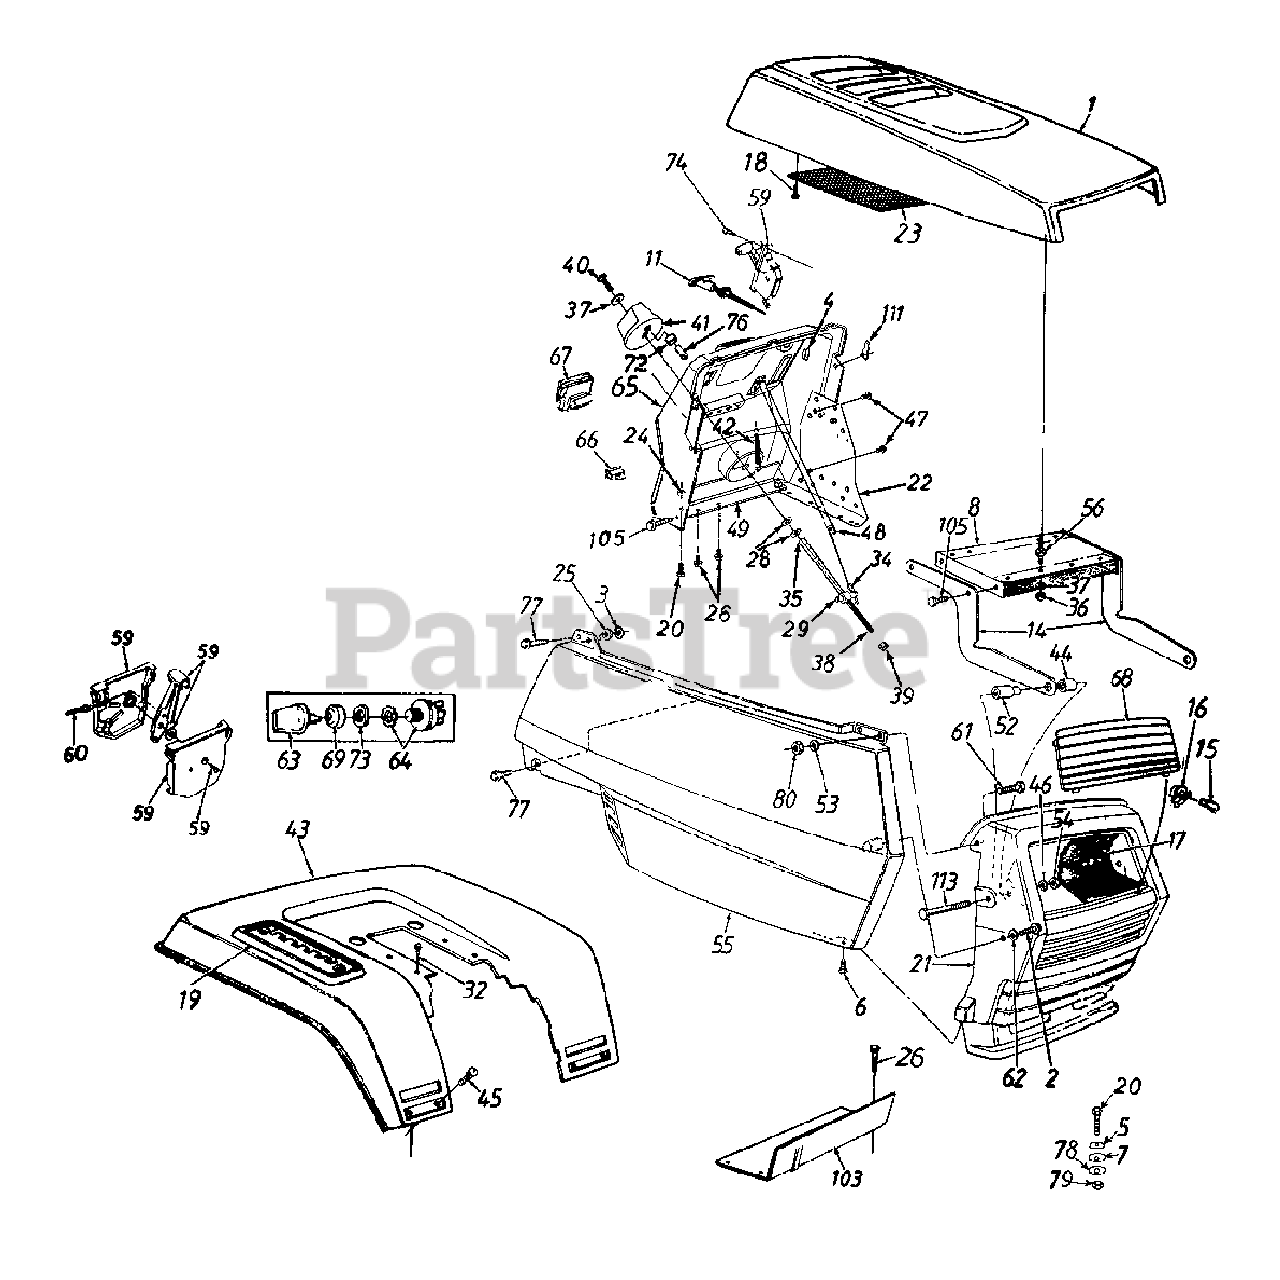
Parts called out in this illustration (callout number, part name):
1	Hood
2	Hex Wash. B-Tap Scr. 1/4 x .62" Lg.
3	Bolt Retainer 1/4" I.D.
4	Retainer Clip
5	FL-Wash. .34" I.D. x 1" O.D.
6	Truss Mach. B-Tap Scr. #10 x .5" Lg.
16	Twist Lock-Lamp Socket
17	Reflector-Headlight
18	Hex Wash. Hd. AB-Tap Scr. #8 x .5" Lg.
19	8-Speed Selector Plate
20	Hex Bolt 5/16-18 x .75" Lg.
21	Grille
24	Hex Sems Nut 5/16-18 Thd.
25	Fl-Wash. 1/4" I.D. x .93" O.D.
26	Hex Wash. Hd. B-Tap Scr. 5/16-18 x .5"
28	Fl-Wash. 3/8" I.D. x .875" O.D.
29	Adj. Ferrule 3/8-8 Thd.
34	Hairpin Clip
35	"E"-Ring .375" Dia.
36	Hex Nut 1/4-20 Thd.
37	Bell-Wash. .265" I.D. x .75"
38	Adjustment Rod
39	Hex Nut 3/8-8 Twin Thd.
40	Hex Bolt 1/4-20 x .75" Lg.
41	Plastic Knob
42	Ext. Spring 3.21" Lg.
45	Carriage Bolt 1/4-20 x .50" Lg.
46	Fl-Wash. .328" I.D. x .68" O.D.
47	Hex Wash. Hd. Scr. 1/4-20 x .5" Lg.
48	Indicator Strip
53	Fl-Wash. .281" I.D. x .5" O.D.
54	Hex Cent. L-Nut 5/16-18 Thd.
55	Side Cover-R.H.
56	Double Ended Stud 1/4-20 Thd.
59	Throttle Control Box Ass'y.
60	Throttle Control Wire 35" Lg.
61	Hex Bolt 1/4-20 x .62" Lg.
62	Fl-Wash. .281" I.D. x .73" O.D.
64	Ignition Switch
65	Dash Panel
66	Light Switch
67	Ammeter
68	Lens
69	Ignition Switch Cap
73	Ignition Switch Nut
74	Truss Mach. AB-Tap Scr. #10 x .5" Lg.
76	Ball Plunger
77	Hex Wash. Hd. Tap Scr. 1/4 x .75" Lg.
78	L-Wash. 5/16" I.D.
79	Hex Nut 5/16-18 Thd.
80	Hex L-Nut 1/4-20 Thd.
111	Speed Nut 1/4-20 Thd.
113	Hex Bolt 5/16-18 x 2.75"
